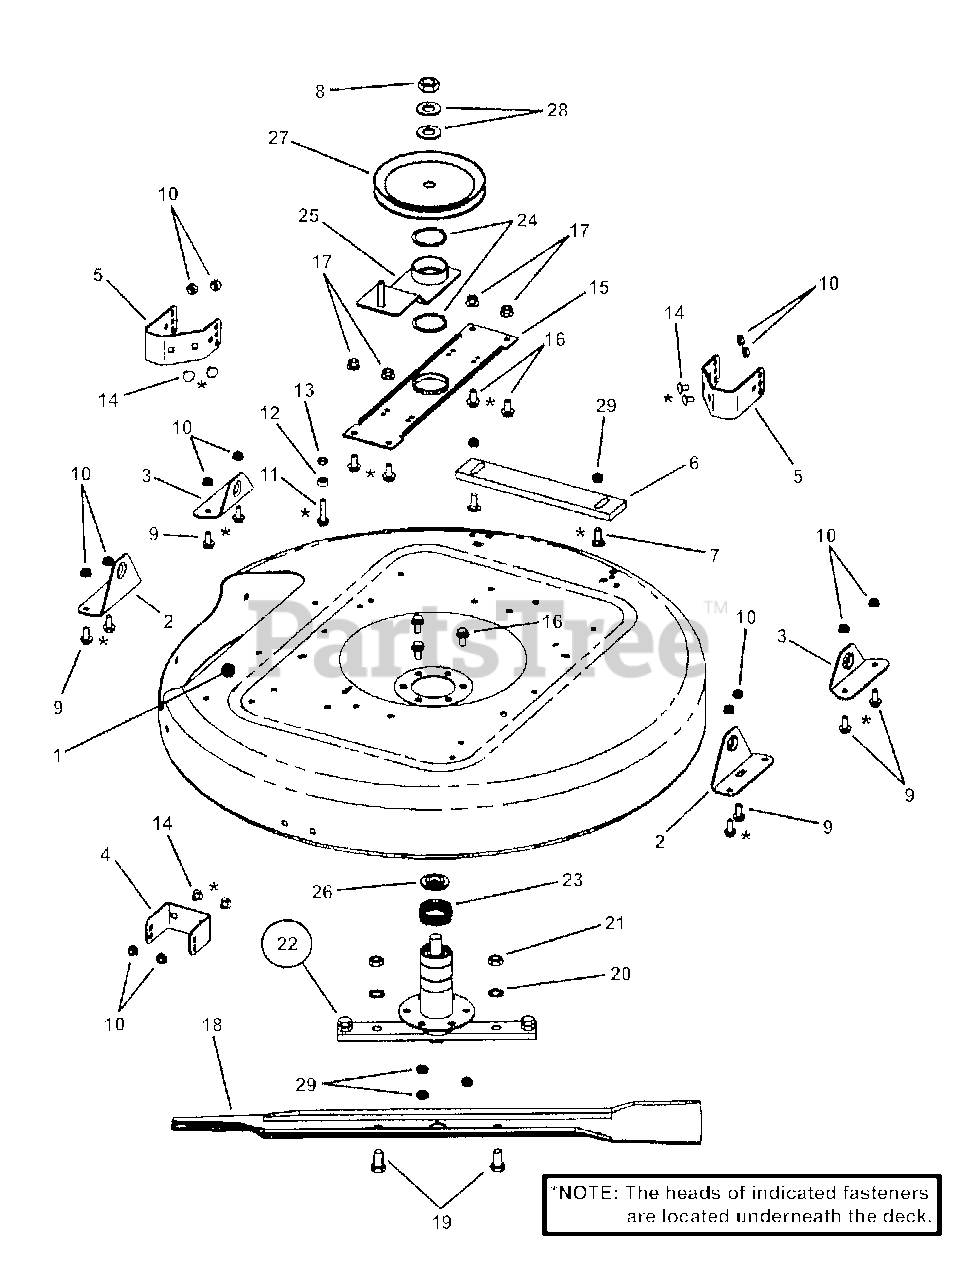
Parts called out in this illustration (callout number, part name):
1	*DECK, 33" Replacement
2	BRACKET, 33 Deck Lift, Slotted
3	BRACKET, 33 Deck Lift
4	BRACKET, Anti-Scalp, Front, Adjustment
5	BRACKET, Anti-Scalp, Side, Adjustment
6	WEIGHT BAR, 33 Rear, HOZ
7	BOLT, 3/8-16 x 1" Square Neck Carriage, GR 5
8	NUT, 3/4-16 Hex Jam, GR 8
9	BOLT, 5/16-18 x 3/4" Hex Flange Lock
10	NUT, 5/16-18 Hex Flange Lock
11	BOLT, 5/16-18 Hex Flange Lock, GR 5
12	SPACER, .340 I.D. x .63 O.D. x .310" thick
13	NUT, 5/16-18 Hex Center Lock, GR B
14	BOLT, 5/16-18 x 1/2" Short Neck Carriage, GR 5
15	BRACE, Spindle
16	BOLT, 3/8-16 x 3/4" Hex Flange Lock, GR 5
17	NUT, 3/8-16 Hex Flange Lock
18	BLADE, 33" High Lift
19	SCREW, 1/2-20 x 1-1/4 Hex Head Cap, GR 5
20	WASHER, 1/2" Internal Tooth Lock
21	NUT, 1/2-20 Hex GR 5 or B
22	ASSEMBLY, Spindle
23	TOLERANCE RING, 2"
24	RING, 2" External Retaining
25	WELDMENT, Idler Arm, 33
26	WASHER, Spindle
27	PULLEY, 33" Spindle
28	WASHER, .781 x 1.5 x .132 Flat
29	NUT, 3/8-16 Hex Center Lock
